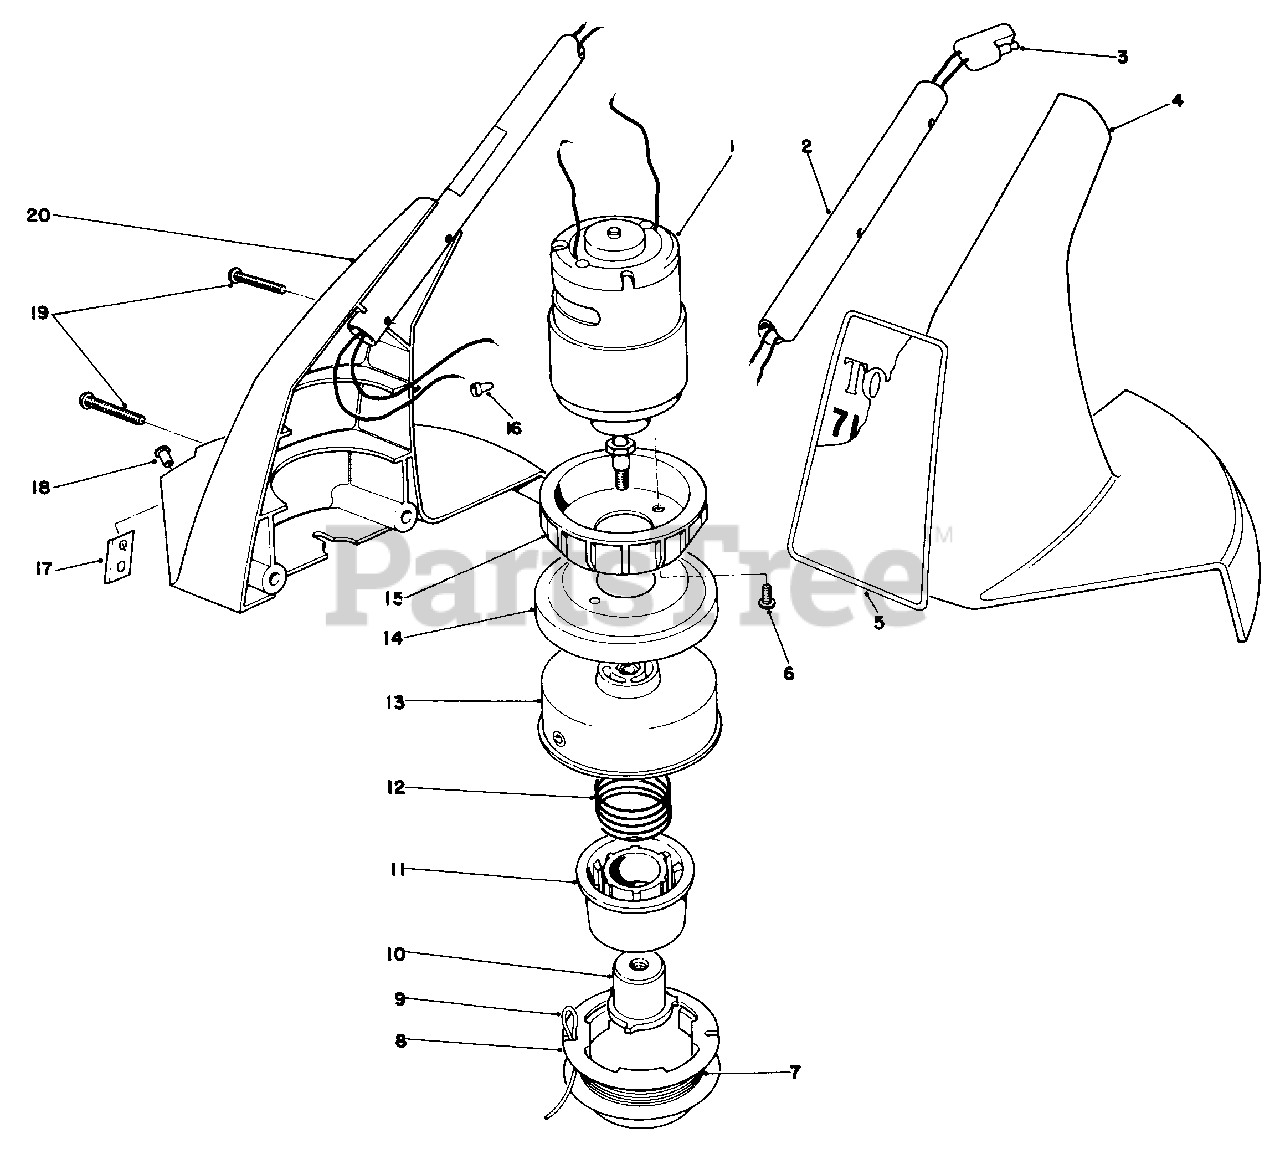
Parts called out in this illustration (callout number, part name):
3	Wiring Harness-Lower
4	Housing-L.H.
5	Decal-Cordless
7	12' .050" Dia. Cutting Line Prewound on Spool
8	Spool-Empty
9	30' .050 " Dia. Cutting Line in Coil
12	Spring
13	Drum w/Eyelet
14	Cup-Drum
15	Casting-Heat Sink
16	Connector-Wire
17	Blade-Knife
18	Rivet
20	Housing-Motor R.H. (Incl. Ref. #17 & 18)
